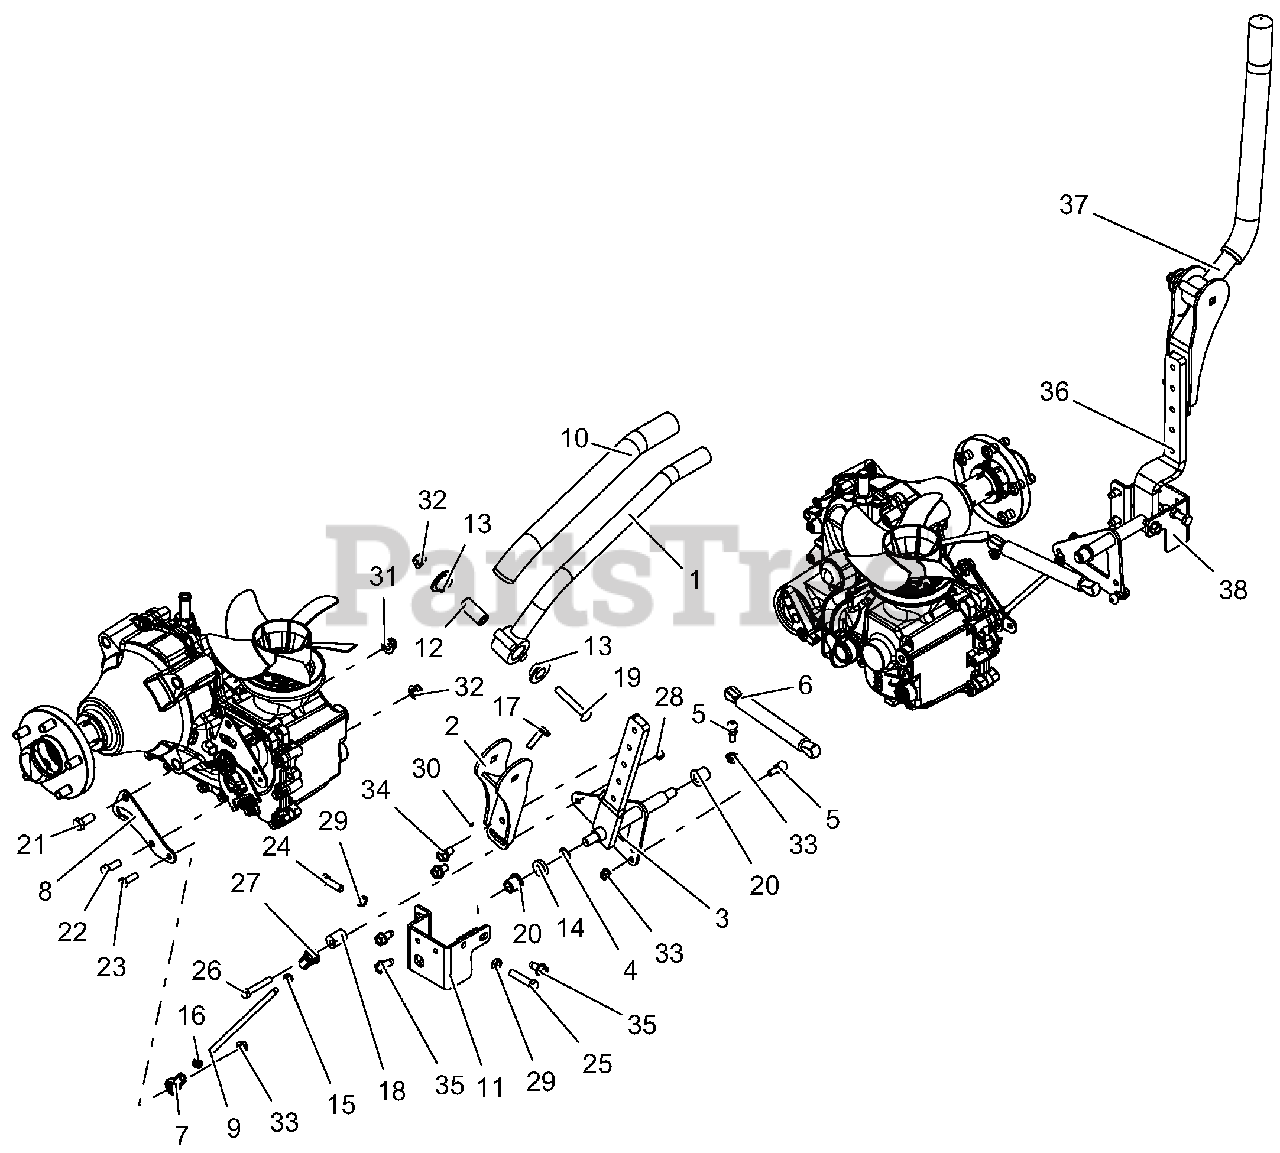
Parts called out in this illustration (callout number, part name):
1	WLDMT, RH STEERING ARM
2	MOUNT, STEERING ARM, ADJUSTABLE-BLACK
3	WLDMT, RH LOWER CONTROL ARM
4	WAVE WASHER .531X.781X.125 FH
5	STUD-BALL
6	DAMPER,
7	ALIGNABALL, 5/16 LH THREAD
8	BRKT., CONTROL MTG-BLACK
9	ROD, STEERING
10	GRIP, HANDLEBAR
11	BRKT, RH CONTROL ARM STOP-RED
12	SPCR, STEERING ARM
13	BSHG, FLANGE .762 X 1.48 X .44 NYLON
15	NUT-JAM
16	NUT, JAM -LH .31-24 YWZC
17	BUMPER, STUD MOUNTED
18	ECCENTRIC
19	BLT-RHDSSQNK .38-16X2.50 G5YZ
20	BHSG-FLG .500X.750X.750X.125
21	BLT-HEX .44-14X1.00 GR5 YWZC
22	BLT-HEX .38-16X1.00 GR5 YWZC
23	BLT-HEX .31-18X1.00 GR5 YWZC
24	BLT-HEX .38-16X1.25 GR5 YWZC
25	BLT-HEX .38-16X1.75 GR5 YWZC
26	BLT-HEX .31-18X2.00 GR5 YWZC
27	ALIGNABALL, 5/16 RH THREAD
28	NUT-LK-CTR .31-18 YWZC
29	NUT, JAM .375-16 YWZC
30	NUT, JAM .312-18 YWZC
31	NUT-LK-NYL-FLG .44-14 YWZC
32	NUT-LK-NYL-FLG .38-16 YWZC
33	NUT, LK-TOP-FLG .312-18 YWZC
34	BLT-SERHFWH .38-16X.62 YWZC
35	SCR-TAP .38-16X.75 HWH TR YWZ
36	WLDMT, LH LOWER CONTROL ARM
37	WLDMT, LH STEERING ARM
38	BRKT, LH CONTROL ARM STOP-RED
